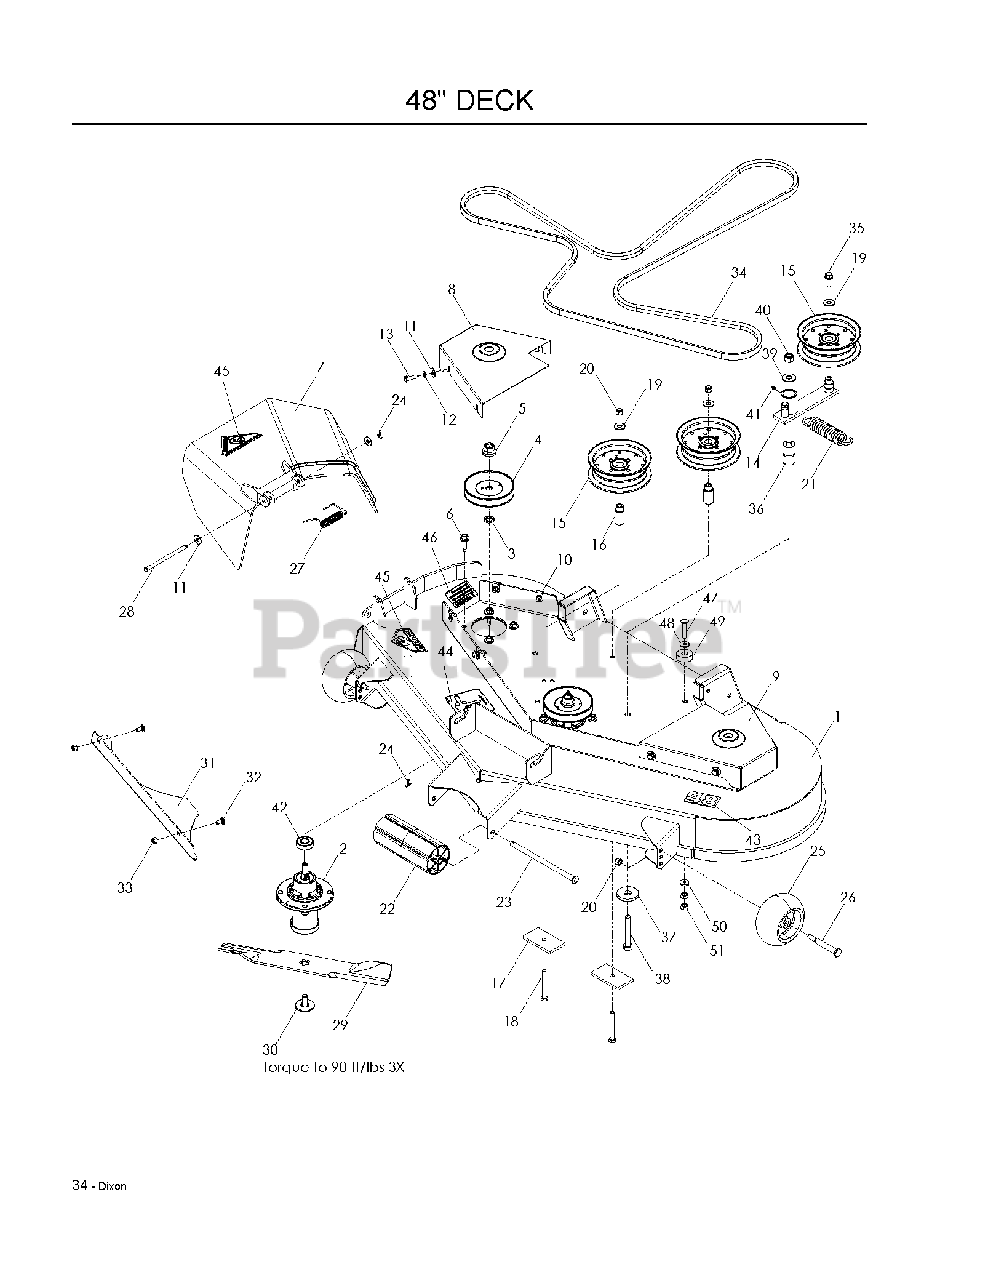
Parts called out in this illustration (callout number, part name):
1	DECK.W/DECALS.RAM.48.BLUE
2	MANDREL.DECK.ASSEMBLY
3	WASHER-SPACER
4	PULLEY
5	LOCKNUT - 9/16
6	WASHER HEAD SCREW
7	DISCHARGE CHUTE 48"
8	BELTSHIELD - R.H. BLUE
9	BELTSHIELD - L.H. BLUE
10	U-CLIP 5/16-18 NUT RETAINER
11	WASHER 5/16 FLAT
12	WASHER 5/16 LOCK
13	HCS 5/16C X 1
14	IDLER ARM
15	PULLEY, IDLER
16	IDLER BUSHING
17	SUPPORT PLATE
18	HCS 3/8C X 3
19	WASHER 3/8 FLAT
20	NUT 3/8-16 NYLOC
22	NOSE ROLLER 48"
23	NOSE ROLLER ROD
24	COTTER PIN 1/8 X 3/4
25	GAUGE WHEEL
26	SHOULDER BOLT 1/2X2-5/8 ZD SPE
27	SPRING - TORSION
28	PIN-CLEVIS 5/16 DIA X 5.19 ZD
29	BLADE, 16-1/4"
30	BLADE BOLT ASSY-7/16" TB REPL
31	Confinement Plate, 48" Black
32	CARRIAGE BOLT 5/16C X 5/8"
33	NUT 5/16 NYLOC
34	BELT, DECK
35	HCS 3/8C X 1 SERRATED HEAD
36	PIVOT BUSHING
37	WASHER, SUPPORT
38	HCS 1/2C X 3 1/4
39	WASHER 1/2 FLAT
40	NUT 1/2-13 HEX NYLOC ZD
41	ZERK
42	BEARING, BALL
43	DECAL, 48"
44	DECAL, BELT ROUTING
45	DECAL, CPSC
46	DECAL, CAUTION
47	RHSNB 3/8-16X1-3/4
48	WASHER 1/2" FLAT
49	ISO-MOUNT BUSHING
50	WASHER 3/8 SAE FLAT
51	NUT 3/8-16 HEX JAM
